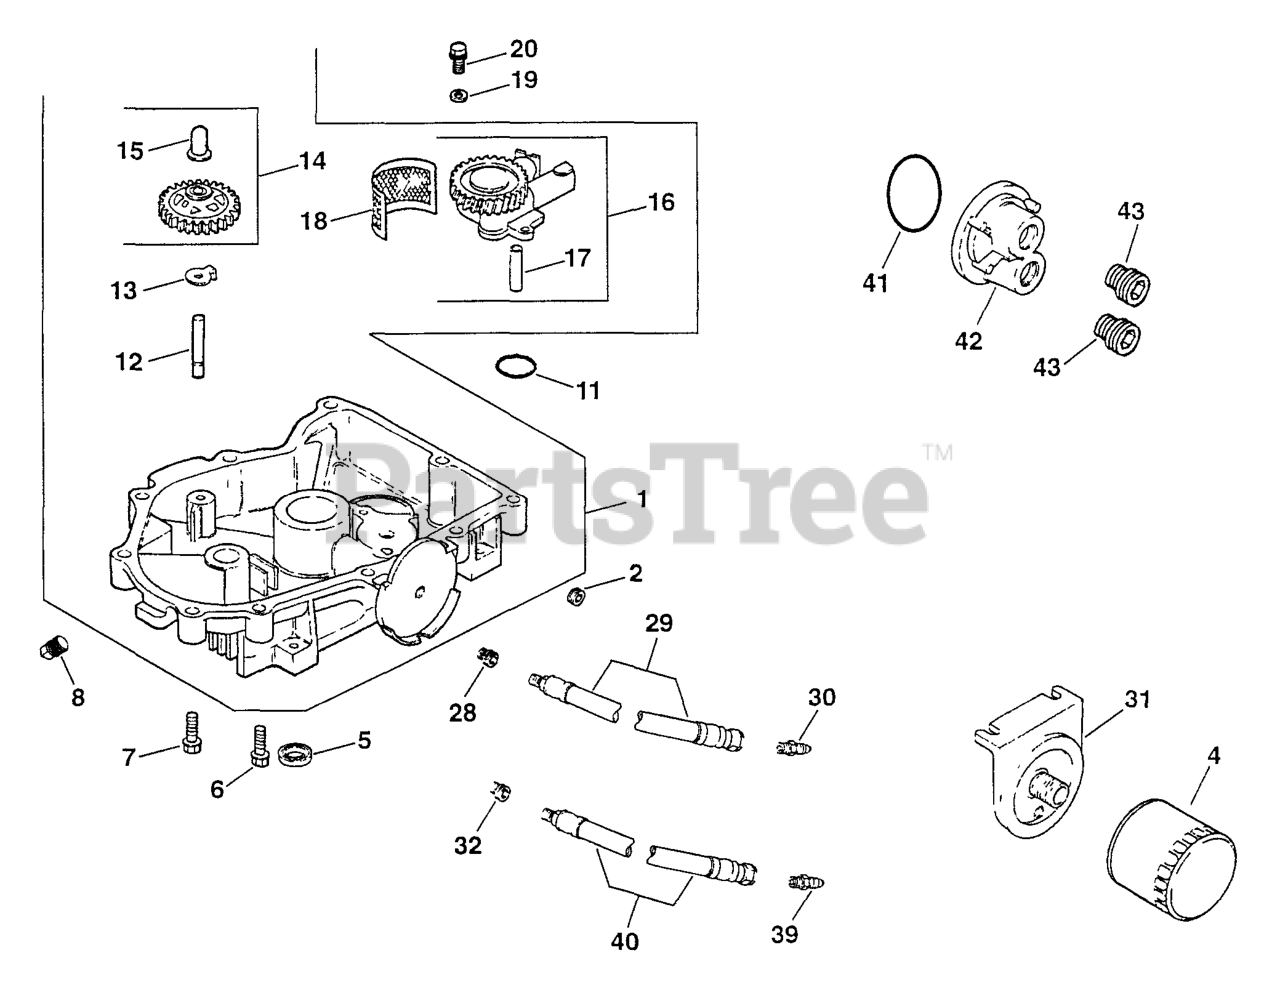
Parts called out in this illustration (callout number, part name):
1	Oil Pan Assembly
2	Plug, Allen Hd. 3/8"
4	Filter, Oil
5	Seal, Oil (Pto End)
6	Screw, Hex. Flange M8x1.25x45
7	Screw, Hex. Flange M8x1.25x45
8	Plug, Sq. Hd. Solid 3/8" N.P.T.F.
12	Shaft, Governor Gear
13	Tab, Locking
14	Kit, Governor Gear W/ Pin
15	Pin, Governor Regulating
16	Oil Pump Assembly (13 Mm)
16	Oil Pump Assembly (17 Mm)
17	Tube, Oil Pickup
18	RING-HANDLE LOCK
19	Washer, Plain 6 Mm
20	Screw, Hex. Flange M6x1.0x25
